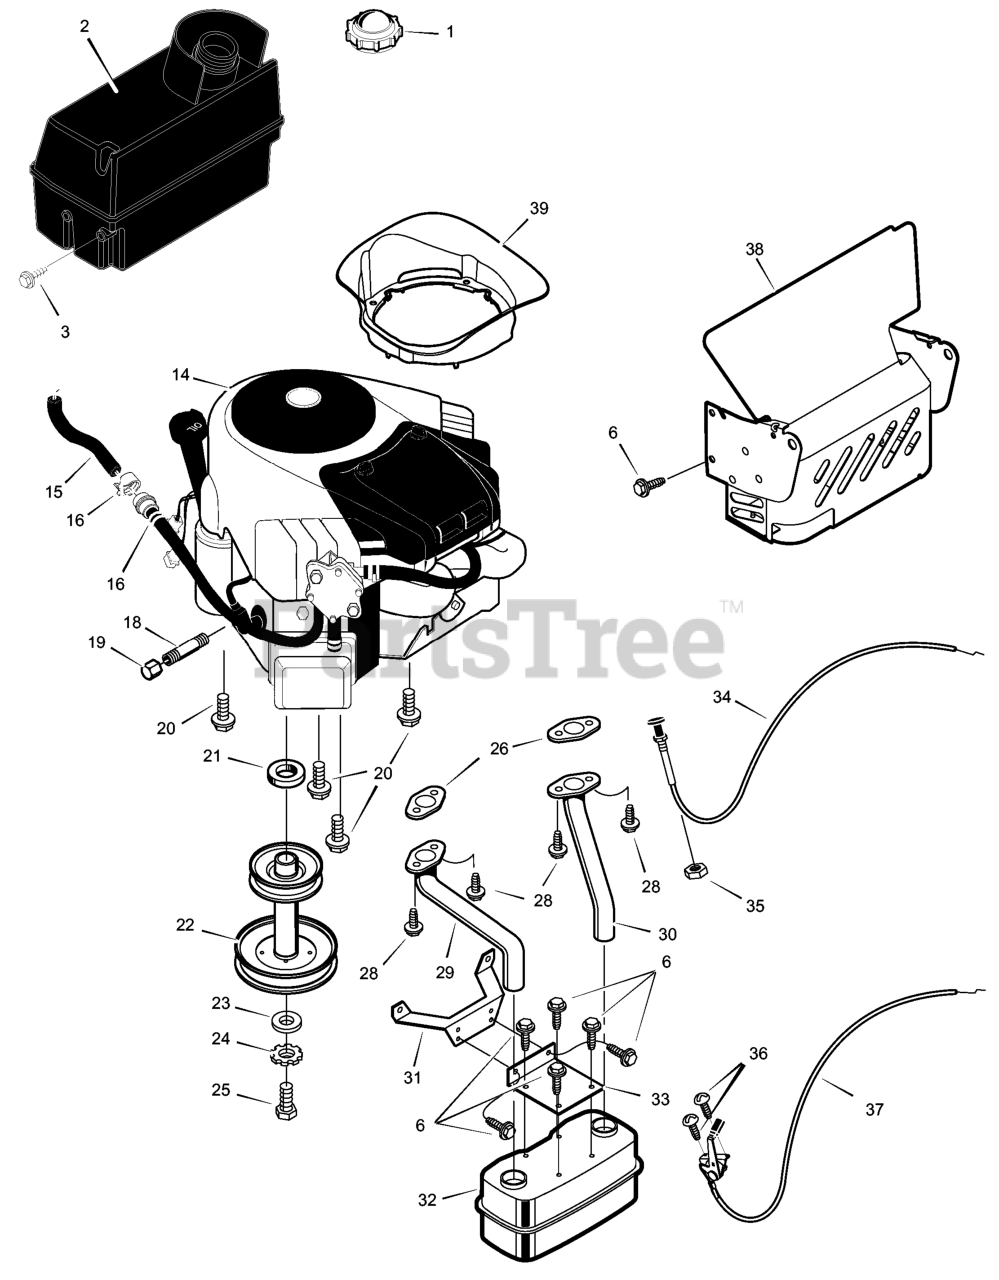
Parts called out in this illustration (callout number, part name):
1	Cap, Fuel
2	Tank, Fuel
14	Engine *
15	Fuel Line (Must cut to length)
16	Clamp
18	Pipe, Oil Drain
19	Cap, Oil Drain
20	Bolt
22	Pulley, Stack
24	Lockwasher
27	Washer
29	Tube, Right Exhaust
30	Tube, Left Exhaust
31	Bracket, Muffler Mount
32	Muffler
33	Bracket, Muffler
35	Nut
37	Control, Throttle
38	Shield Assembly, Heat
